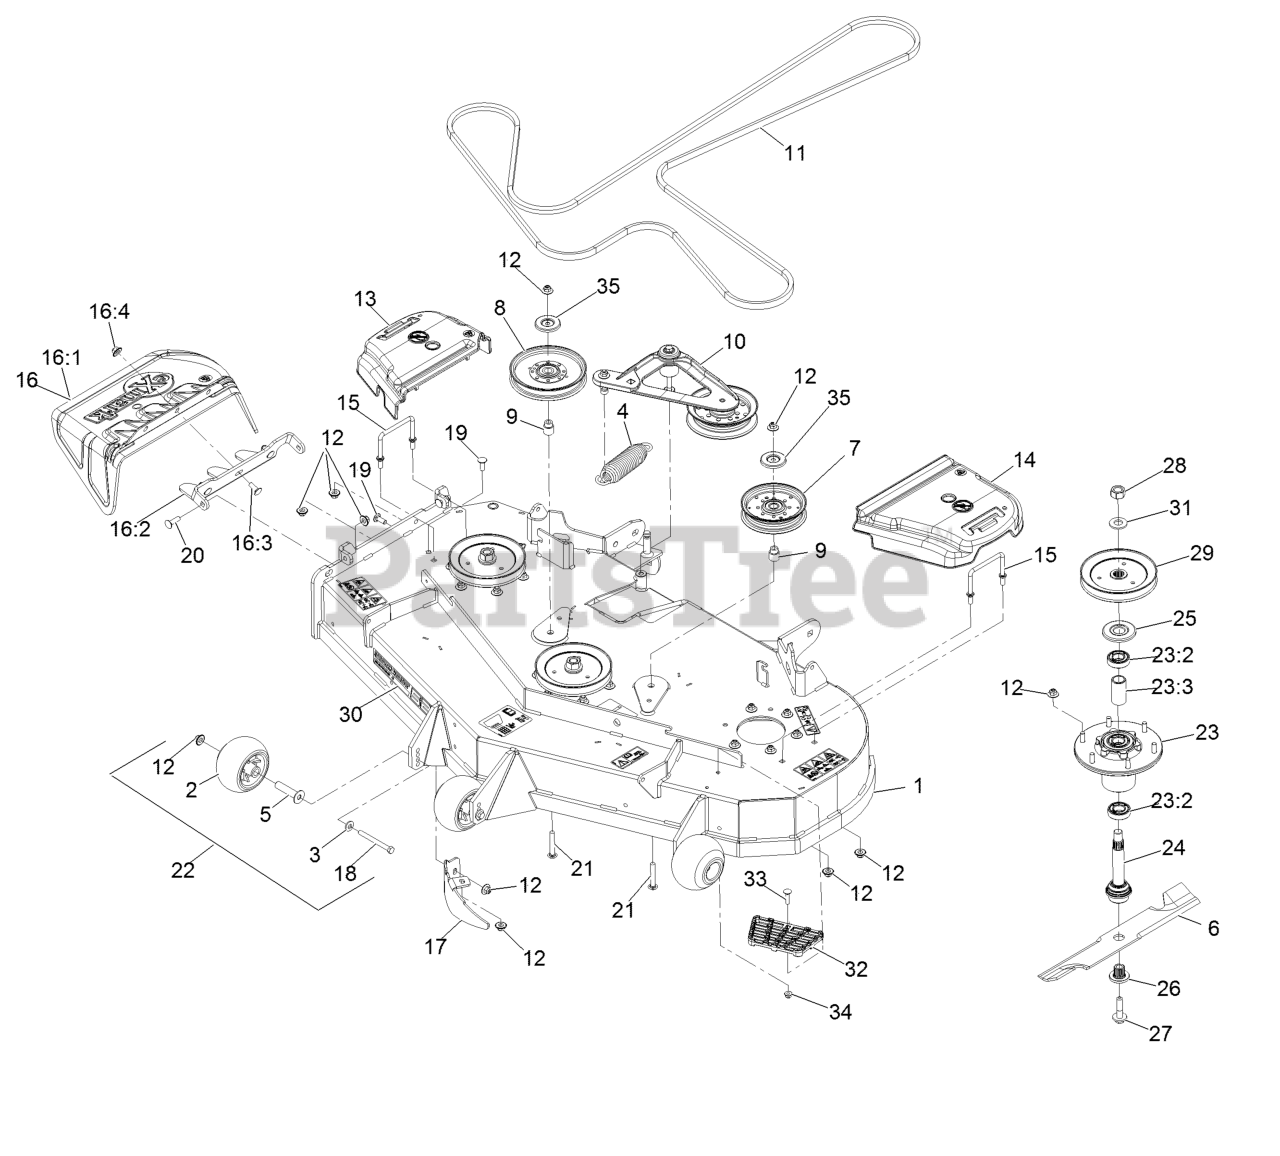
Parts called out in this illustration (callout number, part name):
1	ASM,Deck W/ Decals 52
2	Roller-Anti-Scalp
3	Washer-Spring Disc 3/8
4	Spring-Extension
5	Axle, Roller
6	Blade, Solid
6	Blade, Low Lift
6	Blade, Mulching
6	Blade-Notched
6	Blade-Extreme 2, 18.00"
7	Pulley-Idler, Flat
8	Idler-Pulley
9	Bushing, Idler
10	Deck Idler ASM
11	Belt,V-B X 186.00"
12	Nut-Nyloc 3/8-16 Flg
13	Cover-Belt, RH
14	Cover-Belt, LH
15	Wireform-Cover
16	ASM,Discharge Chute
16:1	Chute, Discharge
16:2	Bracket,Discharge Chute
16:3	Bolt-Carriage 3/8-16 X 1
16:4	Nut-Nyloc 3/8-16 Flg
17	Baffle-Dogleg, Lz-Vt52
18	Screw-HH 3/8-16 X 3 3/4 GR 8
19	Bolt-Carriage 3/8-16 X 1
20	Bolt-Carriage 3/8-16 X 1 1/4
21	Bolt-Carriage 3/8-16 X 2 1/2
22	Kit, Anti-Scalp Roller
23	ASM-Cutter Hsg With Bearings
23:2	Bearing-Ball
23:3	Spacer-Bearing
24	ASM-Spindle And Seal
25	Guard,Bearing Top .989
26	Bushing, Splined
27	Screw-Sems 1/2-20 X 2.19
28	Nut-Hex
29	Sheave,Blade Drive 6.50
30	Decal, 524
31	Washer-Spring Disc 3/4
32	Step-Deck
33	Bolt-Carriage 5/16-18 X 1 1/4
34	Nut-Nyloc 5/16-18 Flg
35	Shield-Dust
